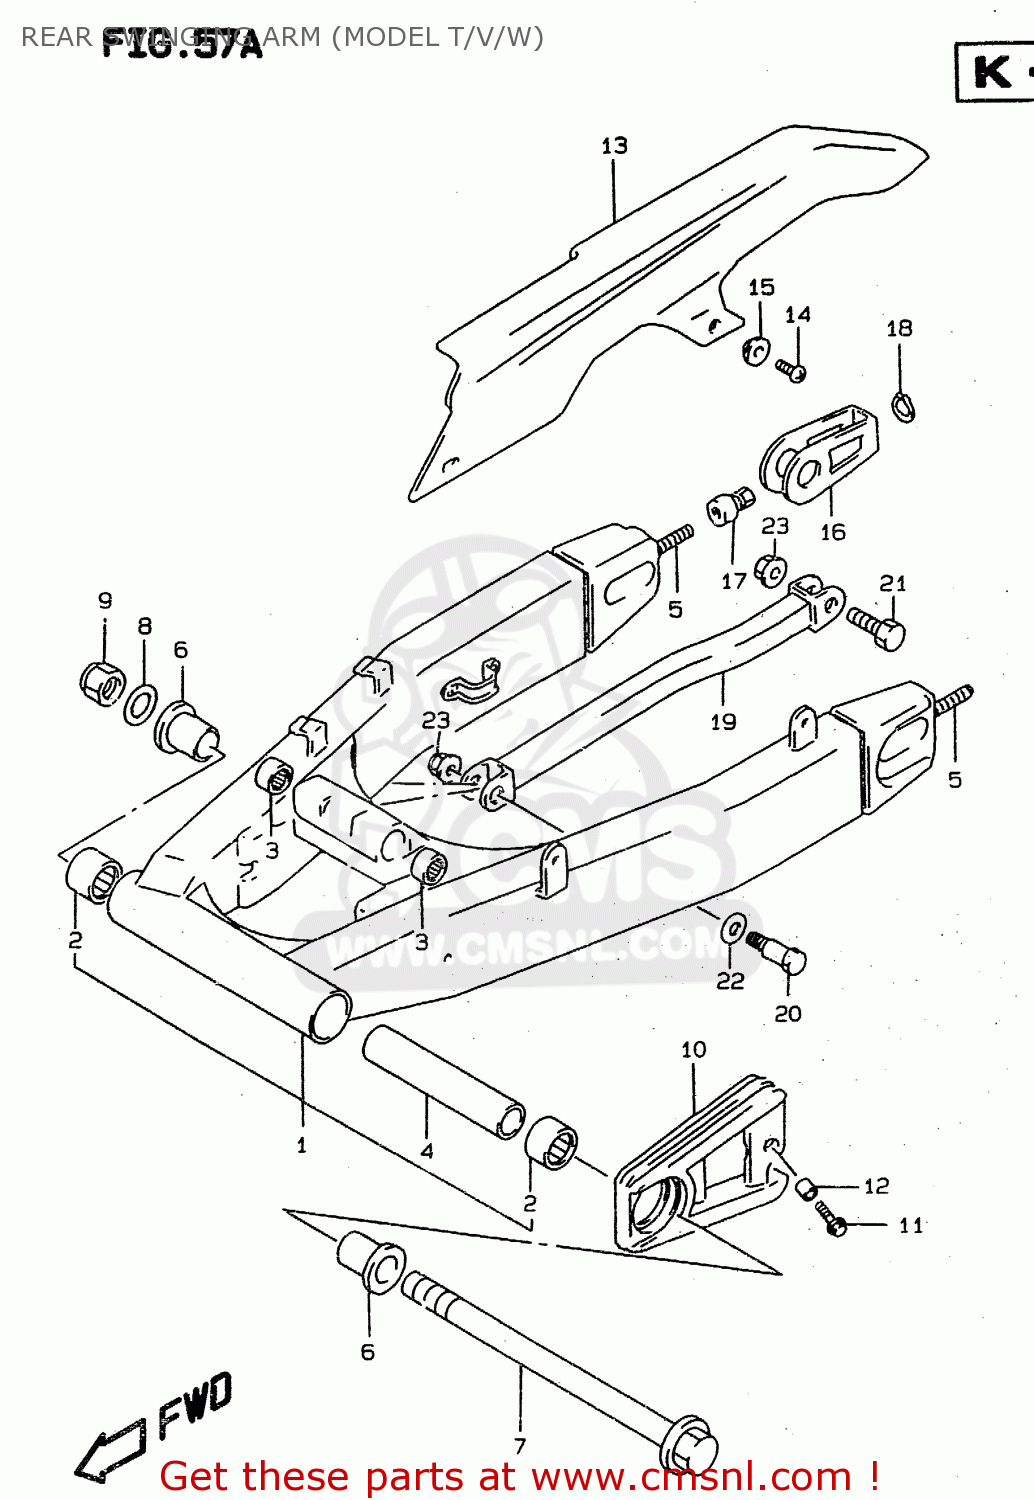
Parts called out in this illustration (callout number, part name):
1	SWINGINGARM ASSY,RR
2	BEARING(25X33X35)
3	BEARING(17X24X25)
4	SPACER,RR SWGARM PIVOT CTR
5	STUD,CHAIN ADJUSTER BOLT
6	SPACER,RR SWGARM PIVOT BERRING
7	SHAFT,RR SWINGINGARM PIVOT
8	WASHER(18.5X28X2.6)
9	NUT
10	BUFFER,CHAIN TOUCH DEFENSE
11	BOLT 6X20,WITH PLAIN WASHER
12	SPACER(6.5X10X7)
13	CASE,CHAIN
14	SCREW 6X12
15	WASHER
16	ADJUSTER,CHAIN
17	NUT,CHAIN ADJUSTER
18	CIRCLIP
19	TORQUELINK,RR
20	BOLT(10X39)
21	BOLT(10X34)
22	WASHER(12.5X20X1)
23	NUT
